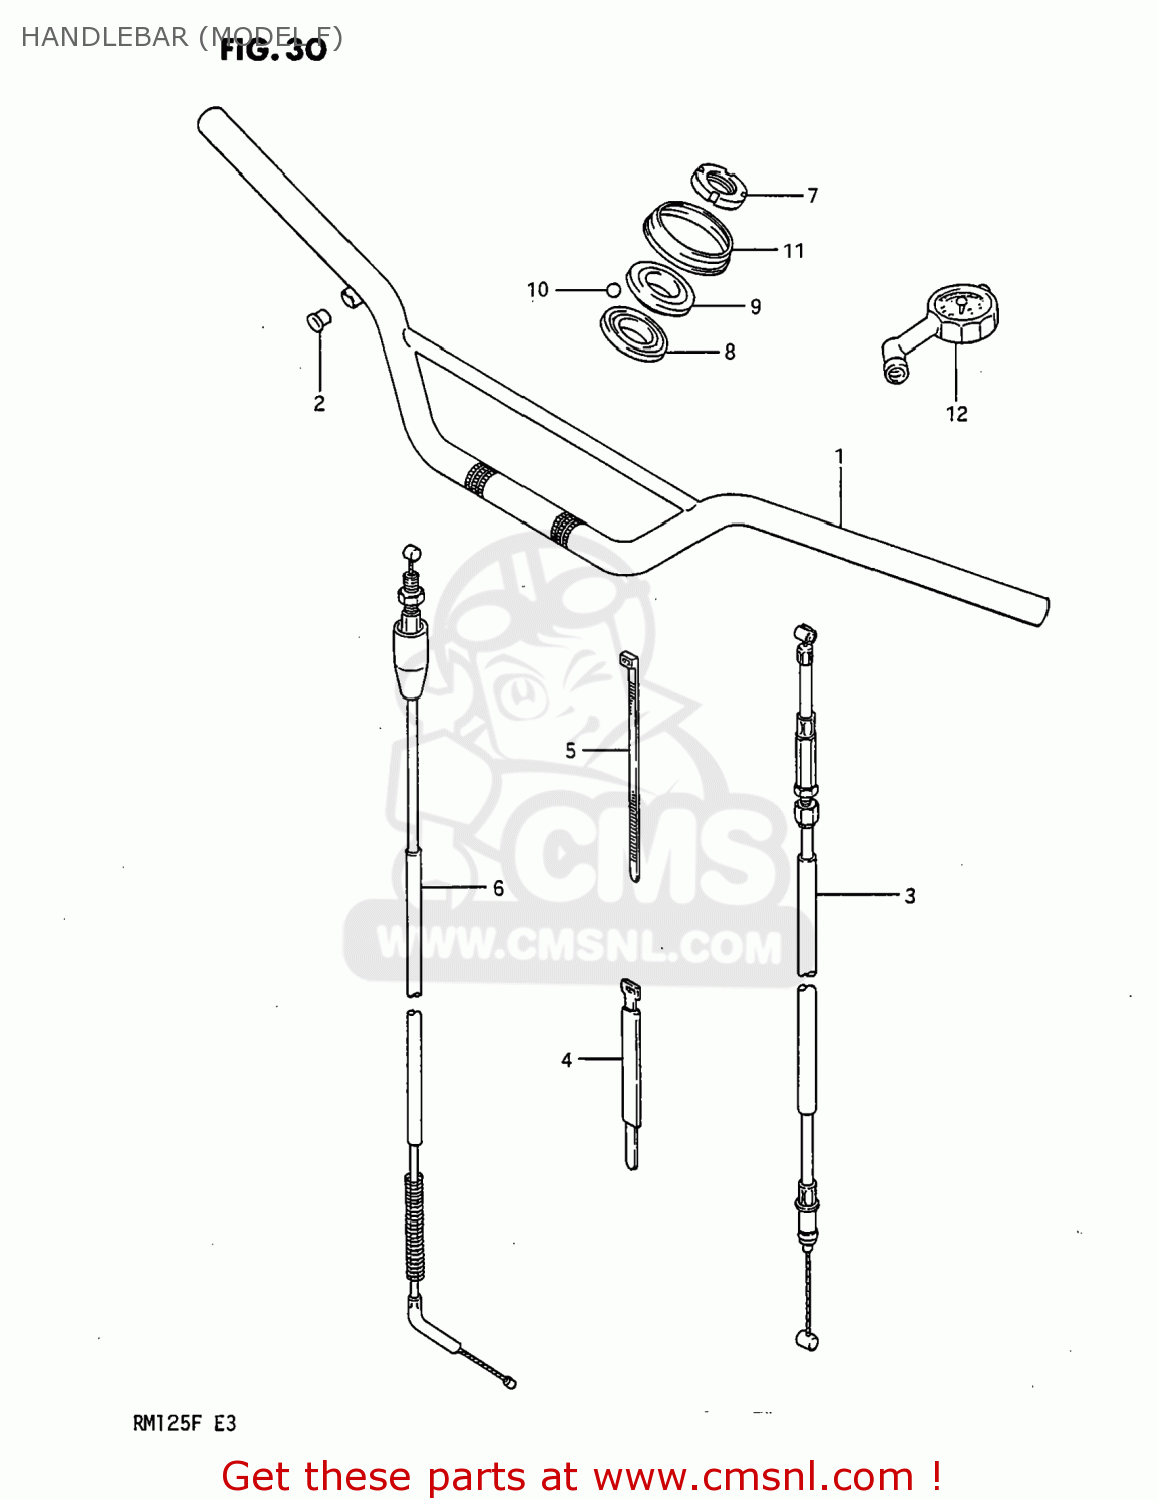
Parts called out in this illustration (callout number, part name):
1	HANDLEBAR
2	CAP(OD:14)
3	CABLE ASSY,CLUTCH
4	CLAMP(L:250)
5	CLAMP(L:235)
6	CABLE ASSEMBLY,THROTTLE
7	NUT,STEERING STEM
8	RACE,STEERING,INNER,UPPER
9	RACE,STEERING,OUTER,UPPER
10	BALL
11	SEAL,STEERING UPR DUST
12	GAUGE ASSY,AIR PRESSURE
